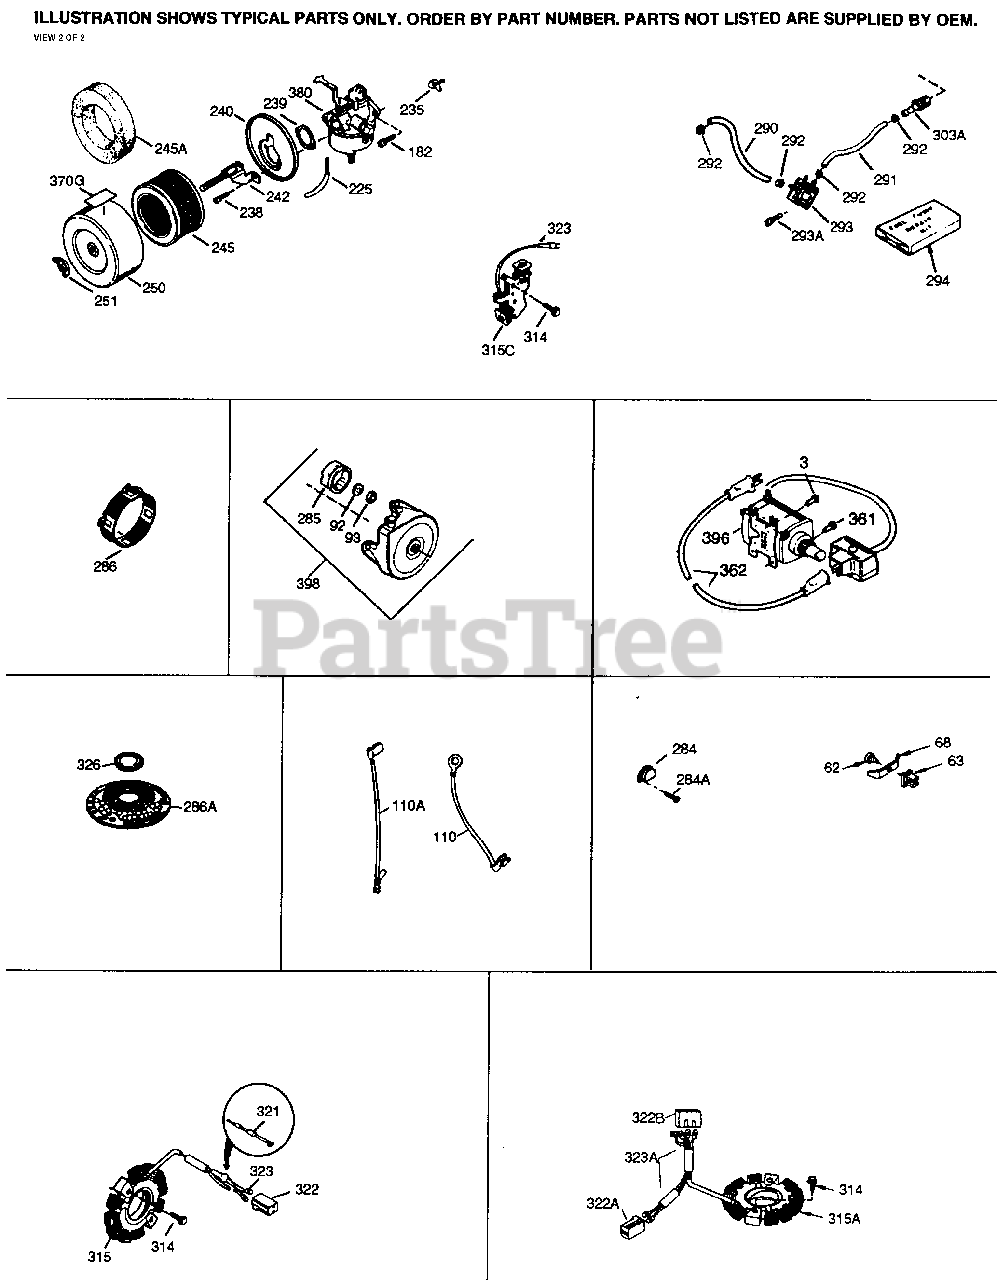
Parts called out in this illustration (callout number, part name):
3	Screw, 1/4-20 x 1/2"
62	Screw, 8-32 x 3/8"
63	Breather Tube Grommet
64	Screw, T-30, 1/4-20 x 1/2"
92	Lock Washer
93	Flywheel Nut
110	Ground Wire (One male, One female, On e eyelet)
110A	Ground Wire
182	Screw, 1/4-20 x 27/32"
285	Starter Cup
286	Starter Screen (Stationary)
290	Fuel Line
292	Fuel Line Clamp
314	Screw, 1/4-20 x 3/4"
315	Alternator Coil (18 Watt) (Incl. 323)
323	Terminal
370D	Warning Decal
370E	Throttle Decal
380	Carburetor (Incl. 184)
396	Electric Starter Motor Kit (120 Volt) (Opt.)
